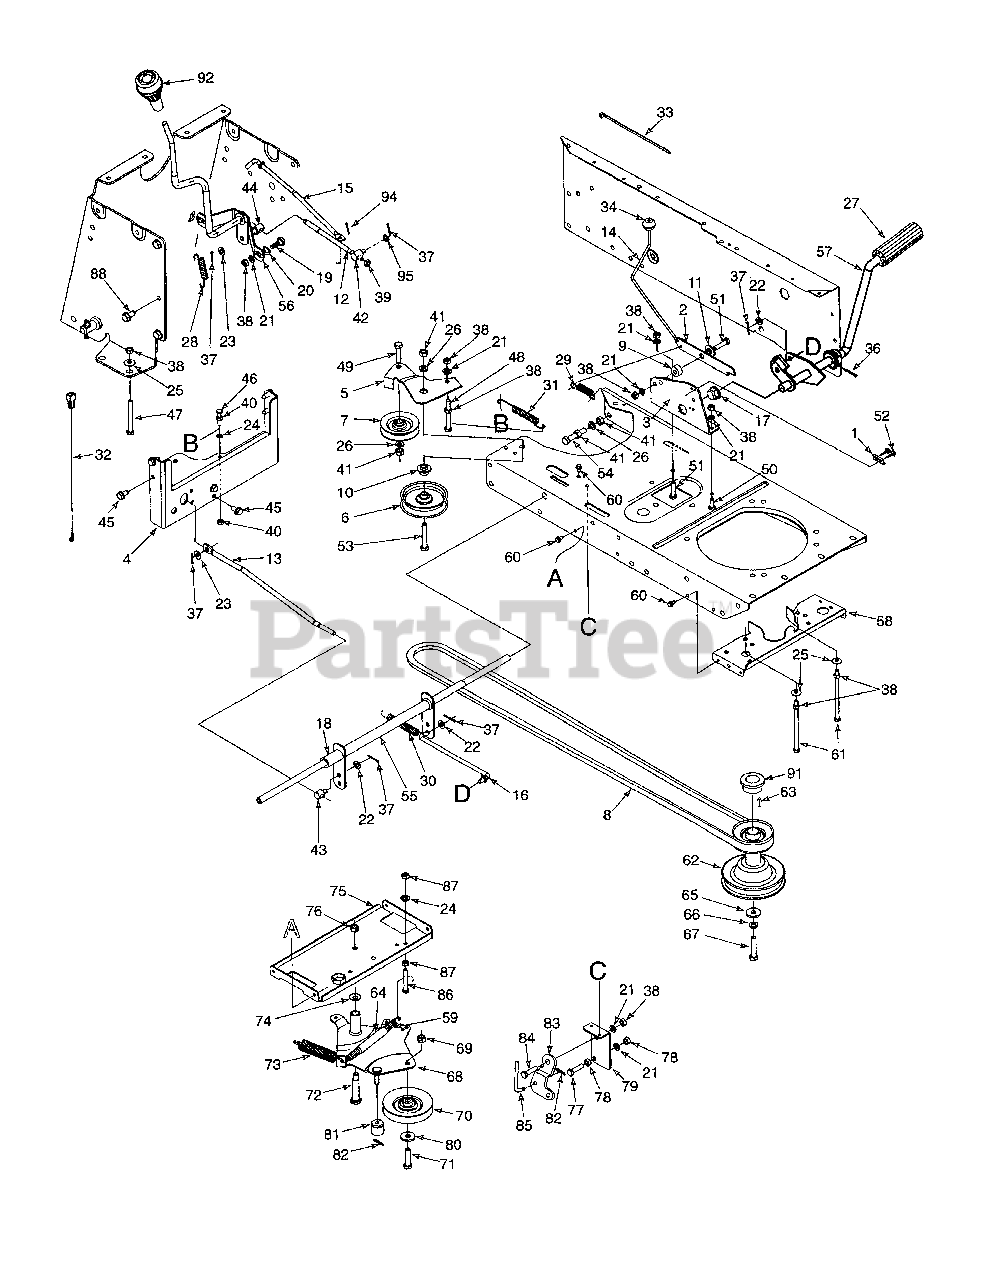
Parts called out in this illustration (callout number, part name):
1	Switch Plate
7	Idler Pulley
8	"V"-Belt
9	Spacer .34" I.D. x .44" Lg.
10	Shld. Spacer .38" I.D.
11	Shld. Spacer
12	Speed Selector Rod
13	Neutral Return Rod
14	Brake Lockout Rod
15	Hydro Disengagement Rod
16	Brake Link Rod
17	Hex Flange Bearing
18	Nyliner Flange Bearing
19	Shld. Bolt
20	Spr. Wash. 7/16" I.D.
21	L-Wash. 5/16" I.D.
22	Fl-Wash. 5/16" I.D.
23	Fl-Wash. .38" I.D.
24	L-Wash. 1/4" I.D.
25	Bell-Wash. .345" I.D.
26	L-Wash. 3/8" I.D.
27	Foot Pad
28	Ext. Spring 2.75" Lg.
29	Ext. Spring 2.51" Lg.
30	Ext. Spring 4.74" Lg.
31	Ext. Spring 4.97" Lg.
32	Transmission Wire
33	Cable Tie
34	Ball Knob
36	Cotter Pin 1/8" Dia. x 1" Lg.
37	Cotter Pin 3/32" Dia. x 1" Lg.
38	Hex Nut 5/16-18 Thd. (Gr. 5)
39	Hex Jam Nut 5/16 Thd. L.H.
40	Hex Nut 1/4-20 Thd. (Gr. 5)
41	Hex Nut 3/8-16 Thd. (Gr. 5)
42	Ferrule 5/16-24 Thd. L.H.
43	Ferrule 5/16-18 Thd.
44	Ferrule 3/8-24 Thd.
45	Hex Wash. TT-Tap Scr. 5/16x .75" Lg.
46	Hex Bolt 1/4-20 x 1.25" Lg.
47	Hex Bolt 5/16-18 x 3" Lg.
48	Hex Bolt 5/16-18 x 2.75" Lg.
49	Hex Bolt 3/8-16 x 1.5" Lg.
50	Hex Bolt 5/16-18 x .75" Lg.
51	Hex Bolt 5/16-18 x 1.25" Lg.
52	Hex HD Tapp Scr. #10-16 x .75" Lg.
53	Hex Bolt 3/8-16 x 2.25" Lg.
54	Hex Bolt 3/8-16 x 2" Lg. (Gr. 5)
57	Hydro Foot Pedal Ass'y.
58	Front Belt Guard
59	Ext. Spring 6.37" Lg.
60	Hex Wash. TT-Tap Scr. 1/4-20 x .5" Lg.
61	Hex Bolt 5/16-18 x 5.25" Lg.
62	Engine Pulley
63	Sq. Key 1/4 x 1.5" Lg.
64	Convoluted Conduit
65	Fl-Wash. .45" I.D. x 1.25"
66	L-Wash. 7/16" I.D.
67	Hex Bolt 7/16-20 x 1.5" Lg.
68	Idler Brkt. Deck Ass'y.
69	Hex Cent. L-Nut 3/8-24 Thd.
70	Idler Pulley
71	Hex Bolt 3/8-24 x 1.5" Lg.
72	Shld. Bolt .498" Dia. x 2.05"
73	Ext. Spring 6.12" Lg.
74	Bell-Wash. .38" I.D. x .88" O.D.
76	Hex Cent. L-Nut 3/8-16 Thd.
77	Hex Bolt 5/16-24 x 1.25" Lg.
78	Hex Nut 5/16-24 Thd. (Gr. 5)
79	Parking Brake Mtg. Brkt.
80	Fl-Wash. .40" I.D. x .875" O.D.
81	Spacer
82	Hairpin Clip
83	Deck Control Pivot Brkt.
84	Shld. Bolt .437" Dia. x .162"
85	Deck Control Rod
86	Hex Bolt 1/4-20 x 2" Lg.
87	Hex Nut 1/4-20 Thd.
88	Hex AB-Tap Scr. 5/16 x .75"
91	Clutch Spacer
92	Shift Knob
94	Hairpin Clip
95	Fl-Wash. .344" I.D. x .75" O.D.
